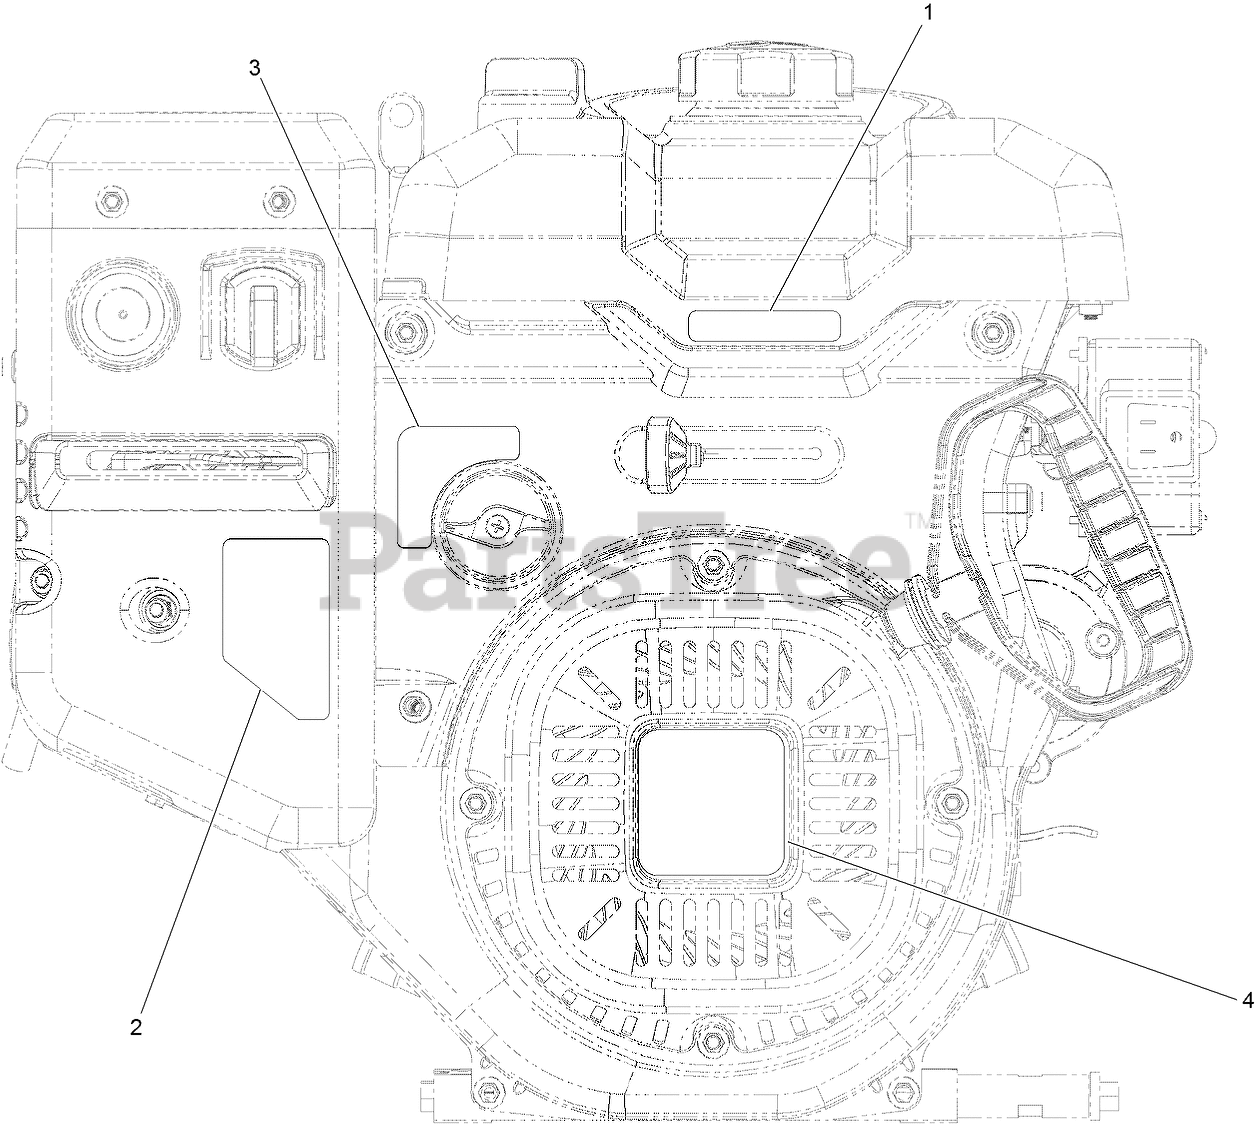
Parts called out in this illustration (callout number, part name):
1	DECAL-THROTTLE
2	DECAL-CONTROL, ENGINE
3	DECAL-VALVE, FUEL
4	DECAL-RECOIL
